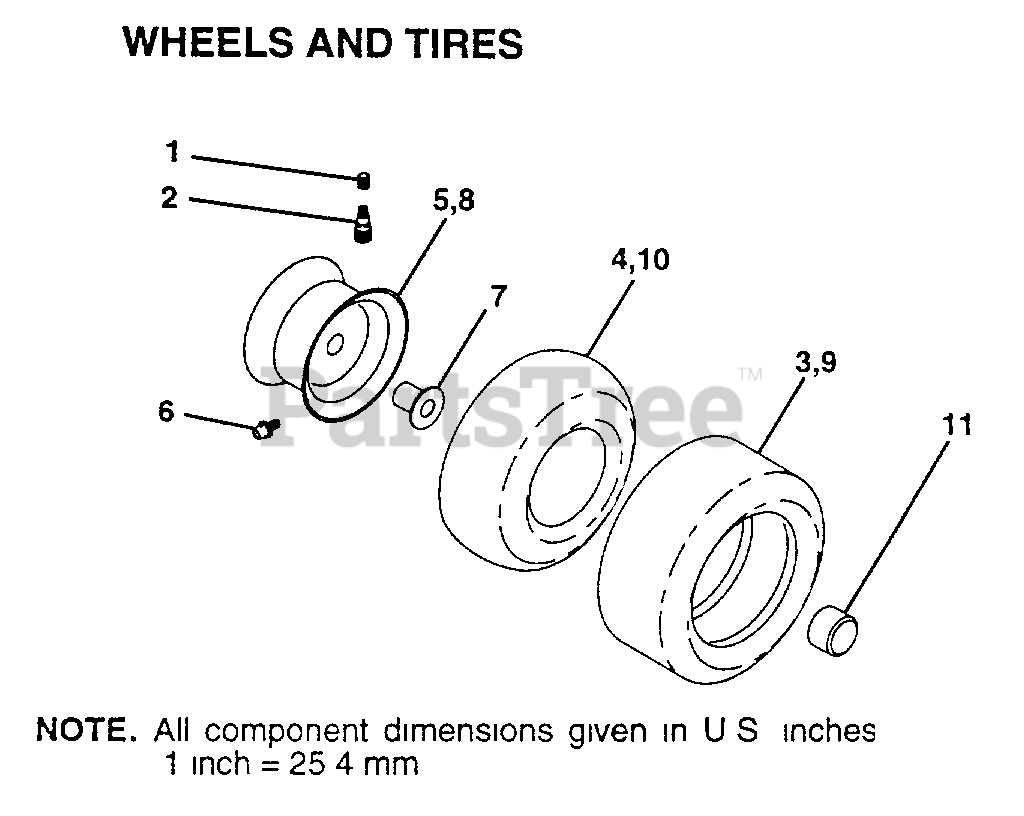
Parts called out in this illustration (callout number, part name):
1	VALVE CAP
2	VALVE STEM LT
4	TUBE.5.3/4.5/6
5	"RIM FRT 6"" ASM"
6	FITTING LT
7	"FLANGE, BEARING"
8	"RIM REAR 8"" ASM"
9	TIRE.20X8-8
10	TUBE.18X9.5-8
11	HUB CAP
